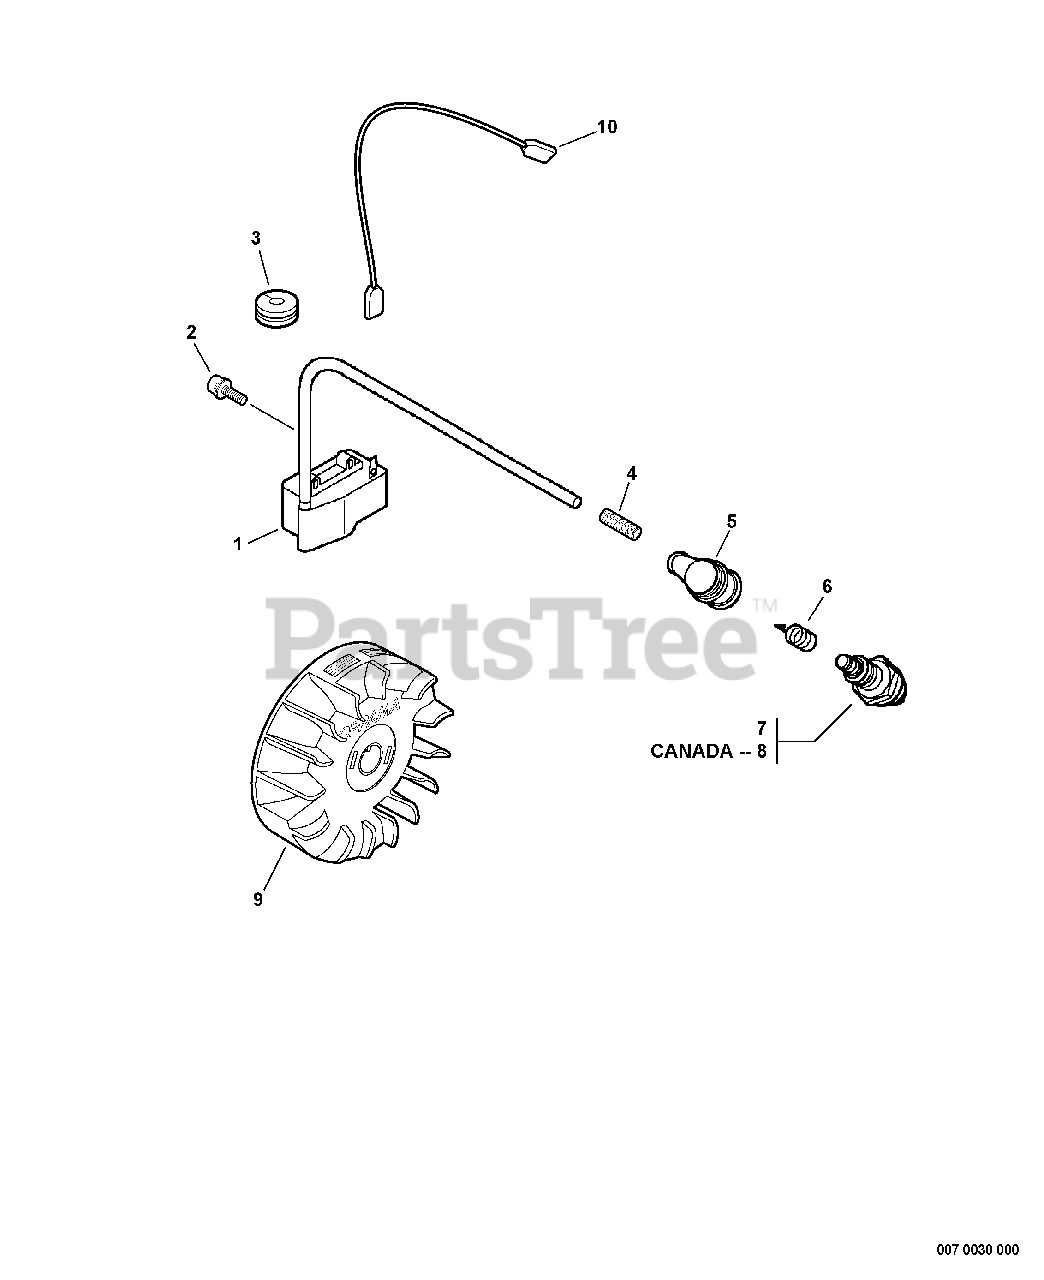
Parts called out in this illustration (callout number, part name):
1	COIL, IGNITION
2	BOLT 4×20
4	TUBE, INSULATOR
5	CAP, SPARK PLUG
6	TERMINAL, SPARK PLUG
7	SPARK PLUG - BPM8Y
8	SPARK PLUG - BPMR8Y
9	FLYWHEEL
10	LEAD - GROUND
